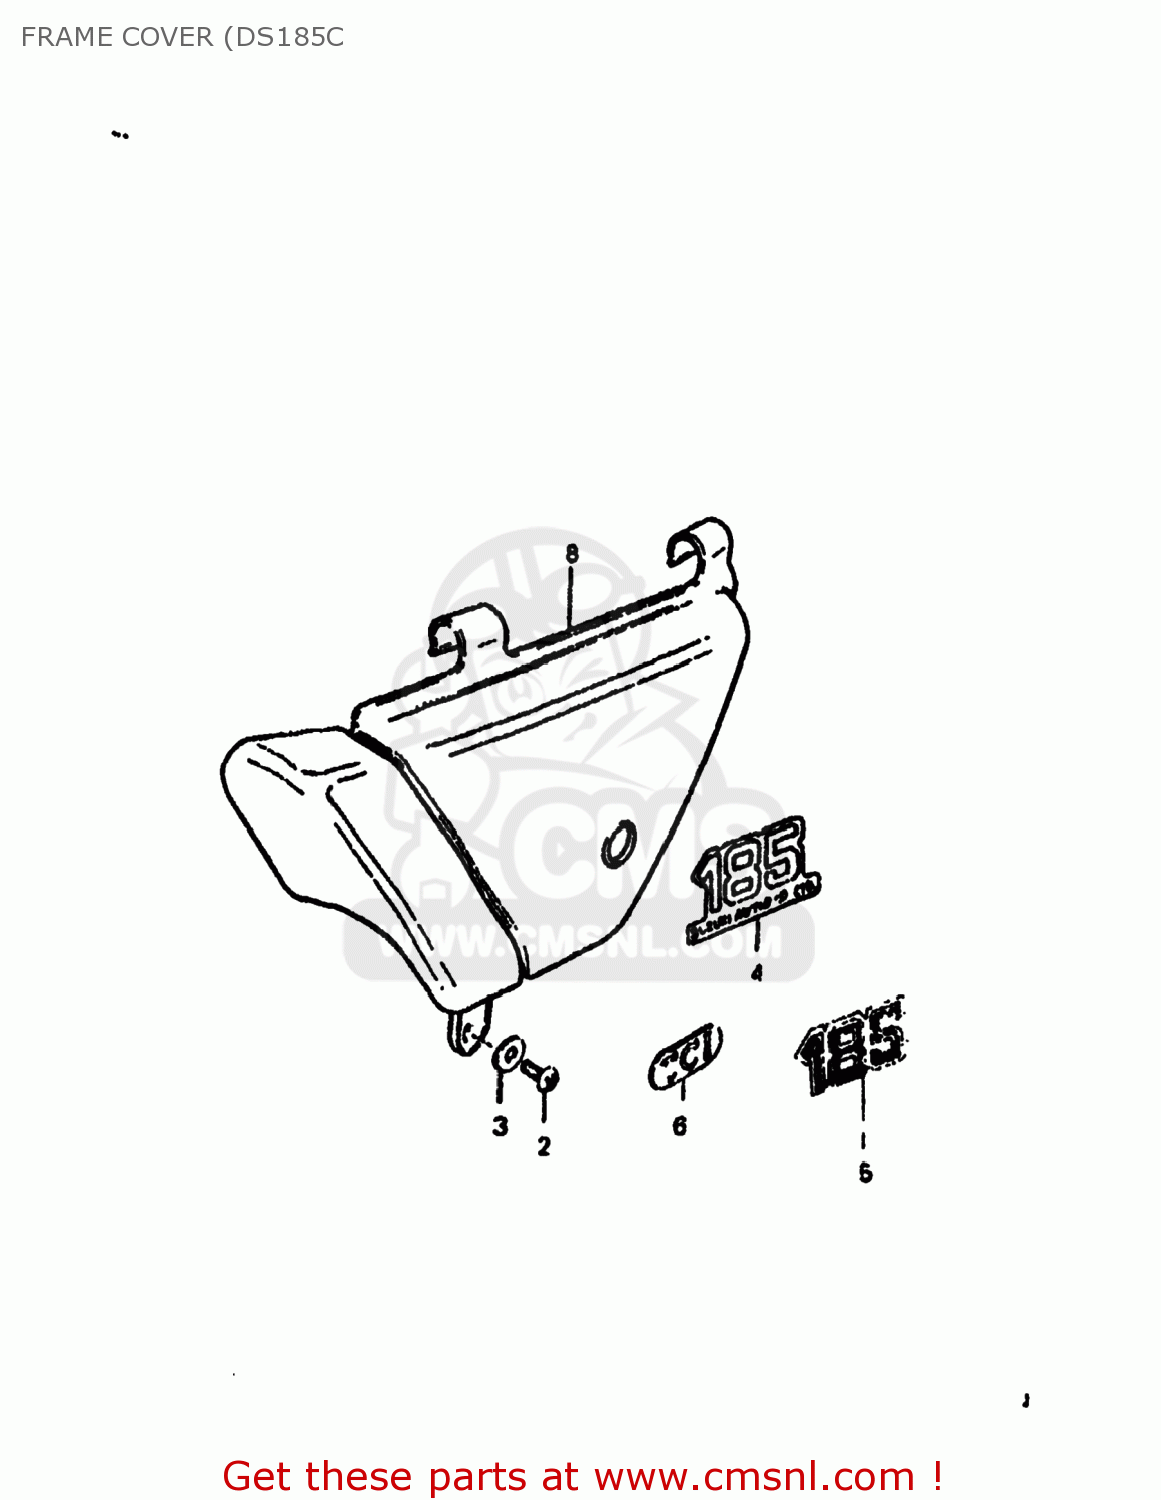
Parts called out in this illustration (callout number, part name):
1	COVER,FRAME,LEFT
2	SCREW 6X12
3	WASHER
4	EMBLEM,FRAME COVER
5	EMBLEM,FRAME COVER
6	EMBLEM,CCIS
